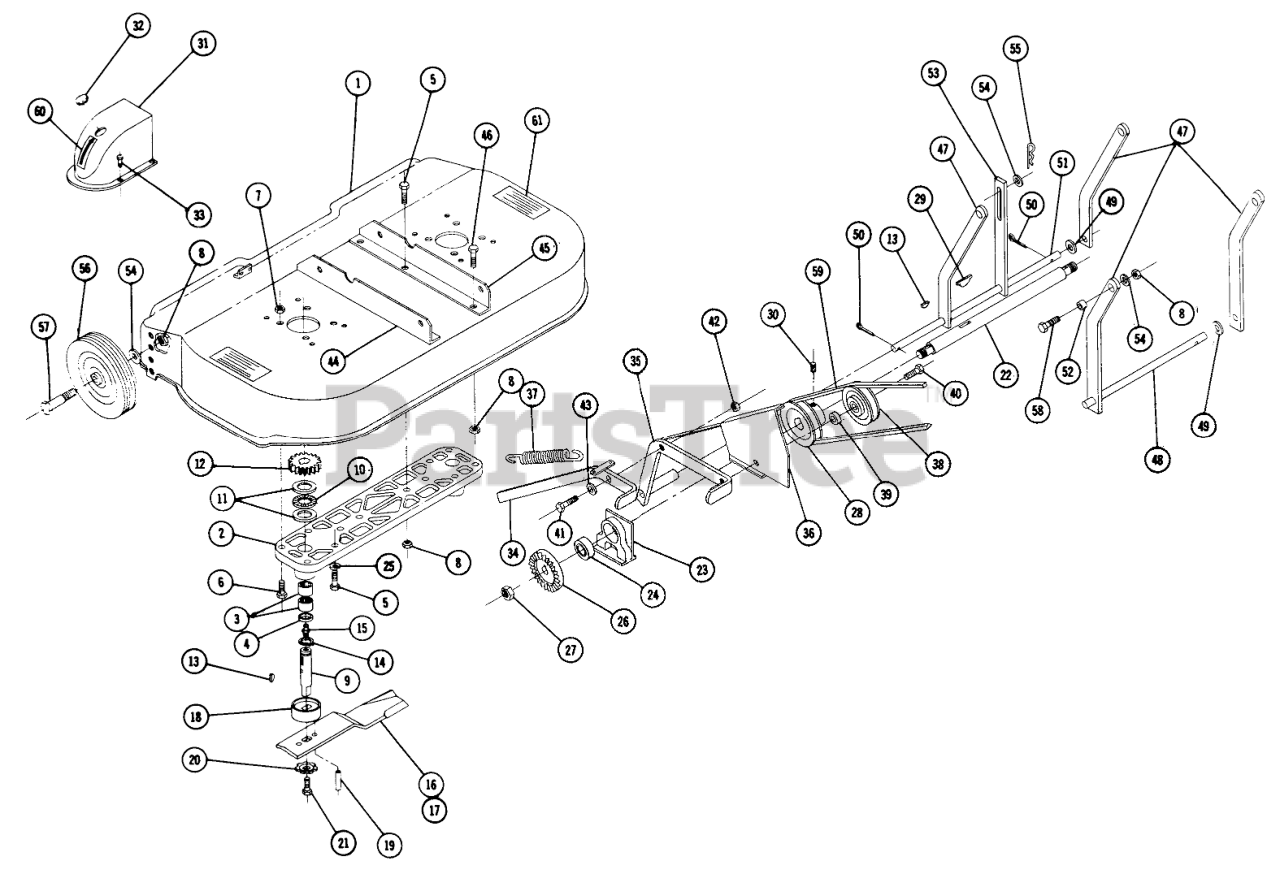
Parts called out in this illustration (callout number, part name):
1	Ass-y. Deck
5	Bolt 3/8-16 x 1
6	Bolt 5/16-18 x
7	Nut-Nylok
8	3/8-16 E.S.
11	WASHER-THRUST
19	SPIROL ROLL PIN
21	Bolt 3/8-16 x 7/8
23	BEARING SUPPORT
25	Lockwasher
30	Set Screw 5/16-18 x 5/16
32	PLUG BUTTON
33	SCREW
35	59027 1969 OPC
40	Bolt 3/8-16 x 7/8
41	Bolt-Hex 1/4-20
42	Nut-Nylok
43	Washer
44	Bracket Mtg. R.H.
45	Bracket Mtg. L.H.
46	Bolt 3/8-16 x 3/4
47	Link-Mower Hanger
49	Washer
50	Cotter Pin
54	Washer
55	Hairpin
57	BOLT-SHOULDER
58	Bolt 3/8-16 x 1
60	Decal
